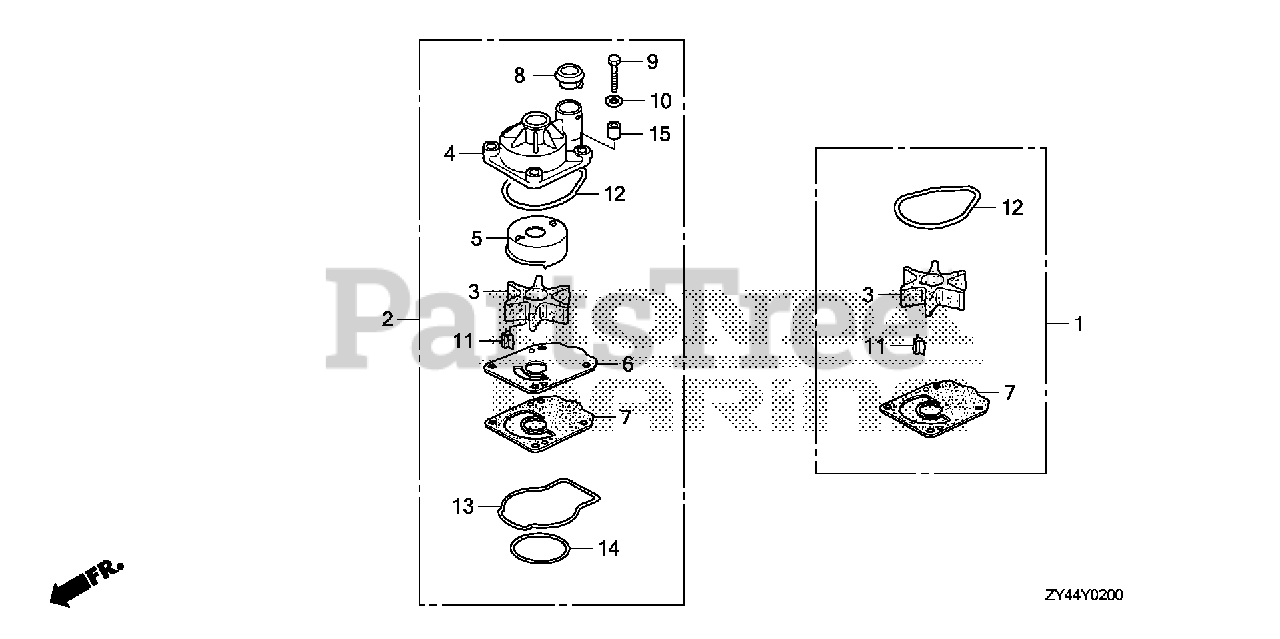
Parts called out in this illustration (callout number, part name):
1	PUMP KIT, IMPELLER
2	PUMP KIT, IMPELLER
3	IMPELLER, PUMP
4	HOUSING, IMPELLER
5	LINER, PUMP
6	COVER, IMPELLER
7	GASKET B, IMPELLER
8	RING, WATER TUBE SEAL
9	BOLT, HEX. (8X60)
10	WASHER (8MM)
11	KEY, WOODRUFF
12	O-RING, WATER PUMP
13	O-RING, WATER PUMP HOUSING
14	O-RING (69.1X2.4)
15	COLLAR, DISTANCE
